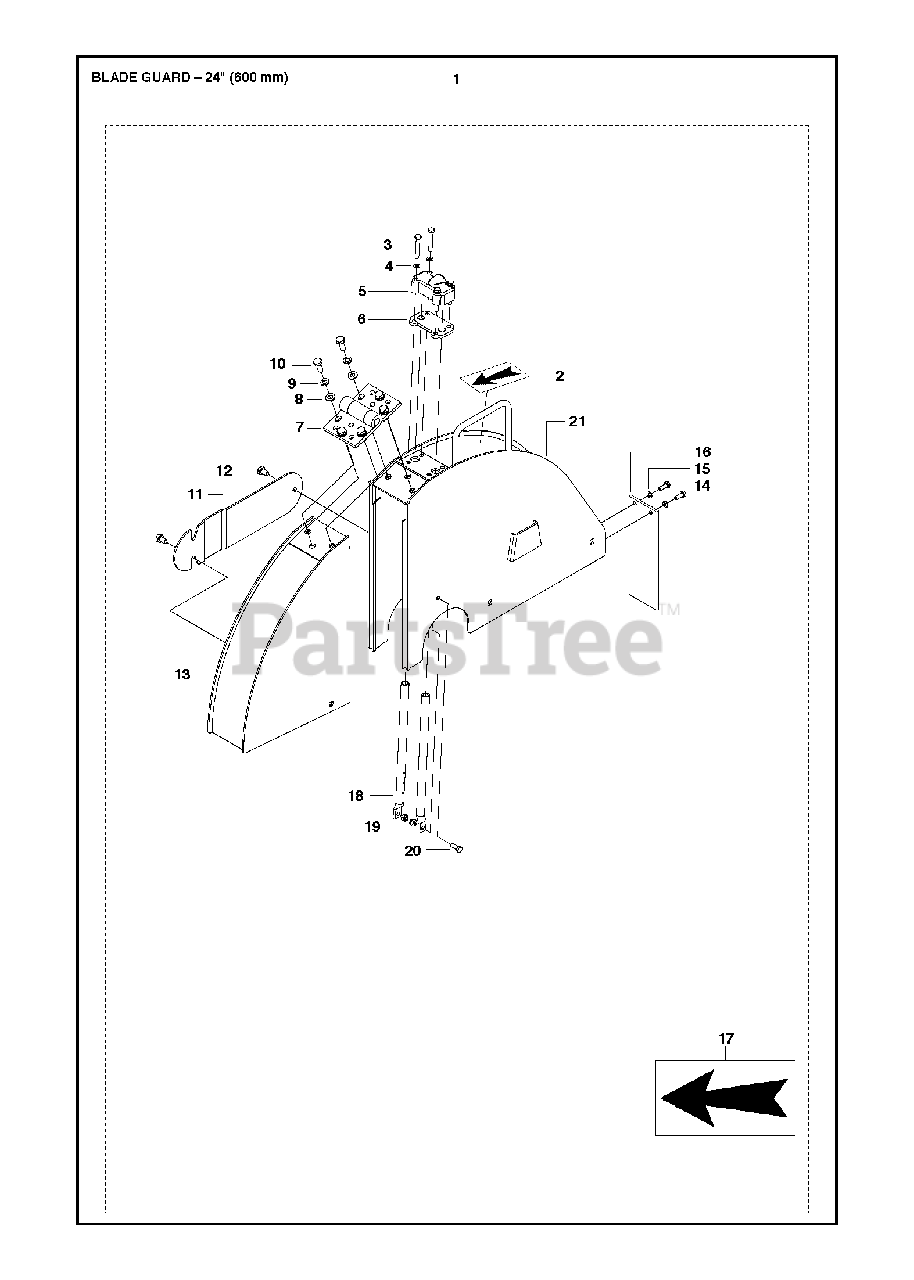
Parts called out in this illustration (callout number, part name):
8	WASHER
9	SPRING WASHER
19	HEXAGON LOCKING NUT
